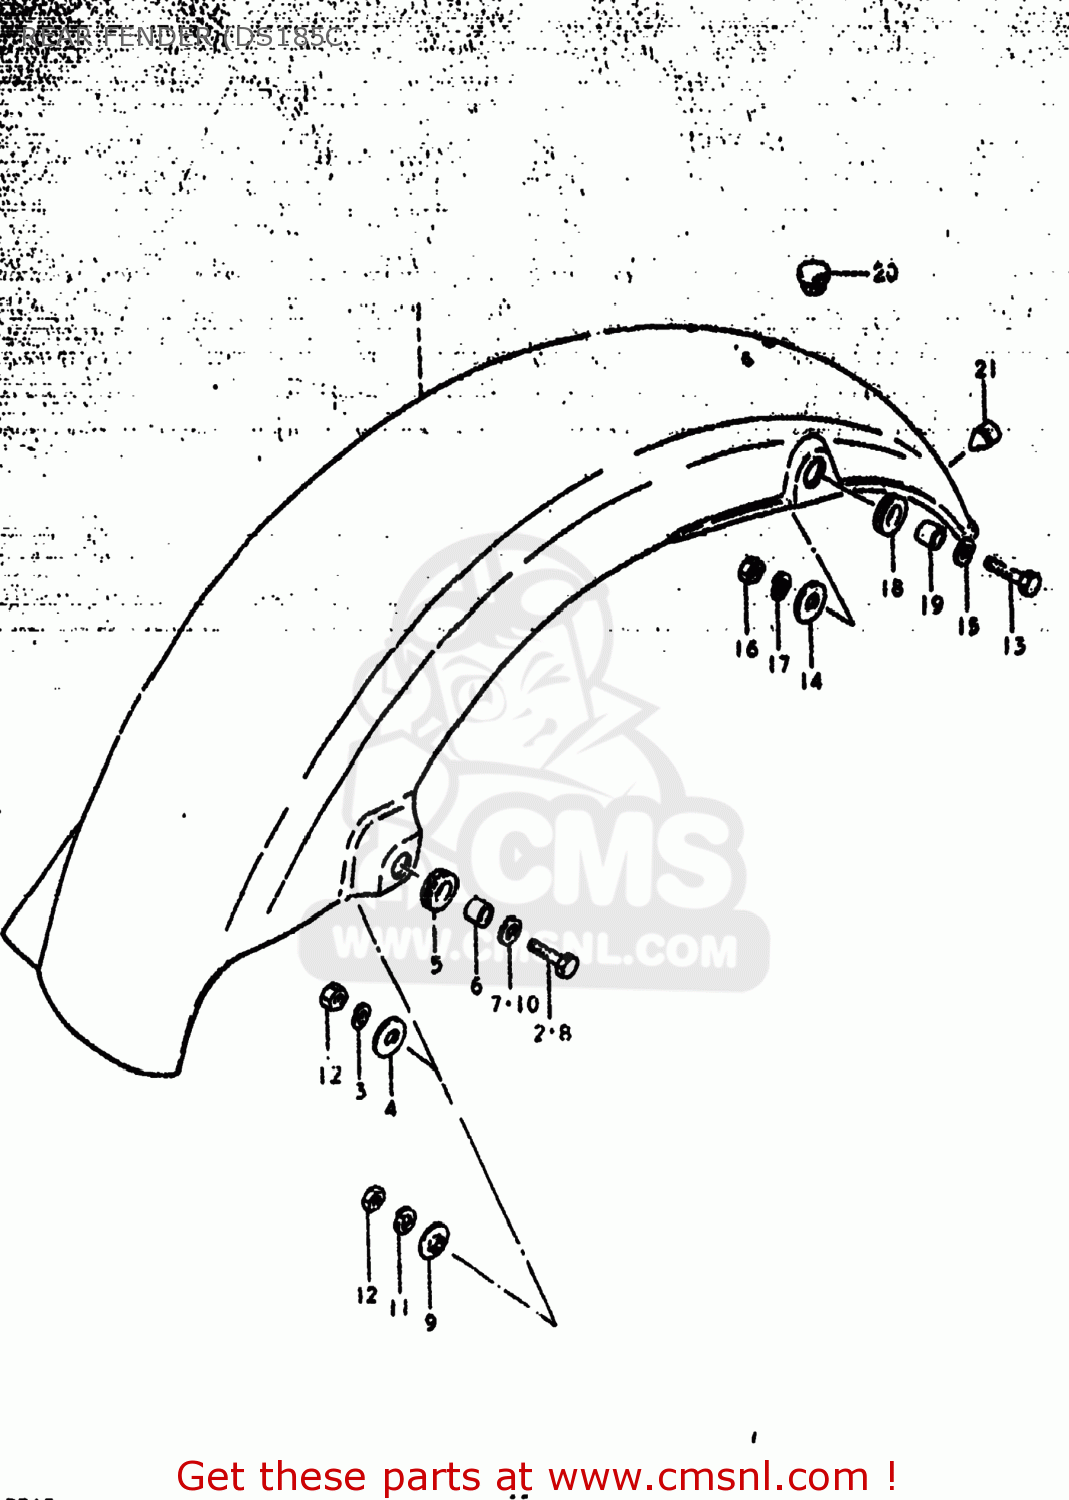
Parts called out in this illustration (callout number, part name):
1	FENDER,REAR
2	BOLT
3	LOCK WASHER
4	WASHER (6.5X20X1.2)
5	CUSHION
6	SPACER(6.1X9X7.5)
7	WASHER
8	BOLT
9	WASHER
10	WASHER
11	LOCK WASHER
12	NUT
13	BOLT (8X30)
14	WASHER(8.5X26X1.2)
15	WASHER
16	NUT
17	LOCK WASHER
18	CUSHION
19	SPACER (8.2X12X7.5)
20	CUSHION
21	CUSHION
